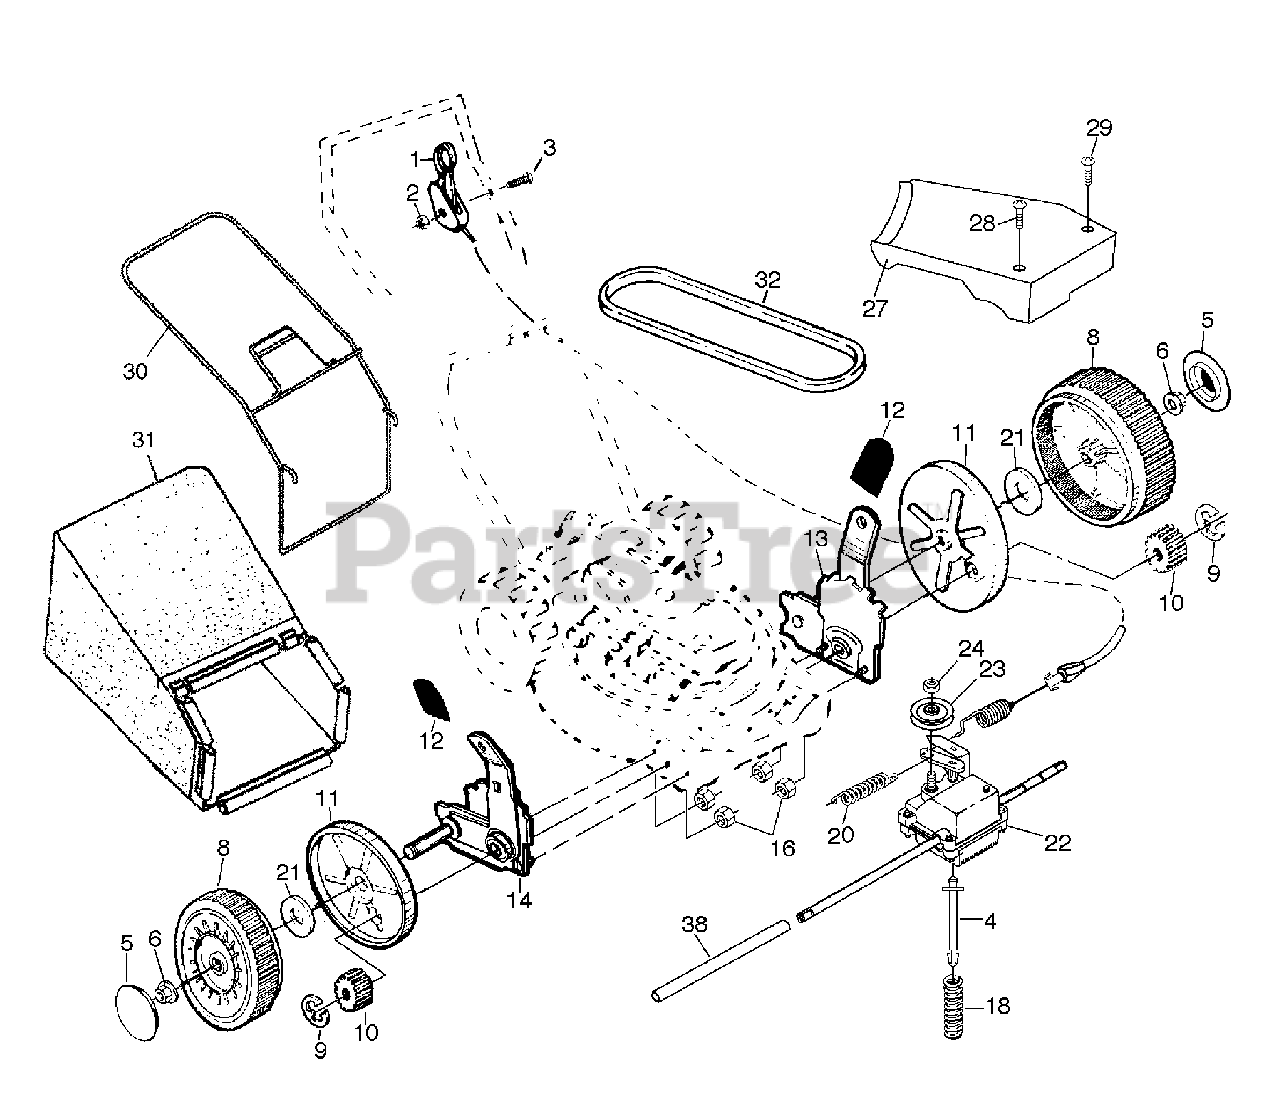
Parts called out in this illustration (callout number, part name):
1	Drive Control
2	Locknut #10-24
3	Pan Head Machine Screw 1/4-20 x 2-1/8
4	Spring Retainer
6	Nut
8	Wheel & Tire Assembly
11	Dust Cover
12	Selector Knob
13	Wheel Adjuster Assembly (Left)
14	Wheel Adjuster Assembly (Right)
16	Locknut
21	Washer 1/2 x 1-1/2 x .134
22	Gear Case Assembly
23	Drive Pulley
24	Locknut
27	Drive Cover
29	Pan Head Tapping Screw #10-24 x 1-3/4
30	Catcher Frame
31	Grass Bag
32	V-Belt
38	Drive Shaft Cover
